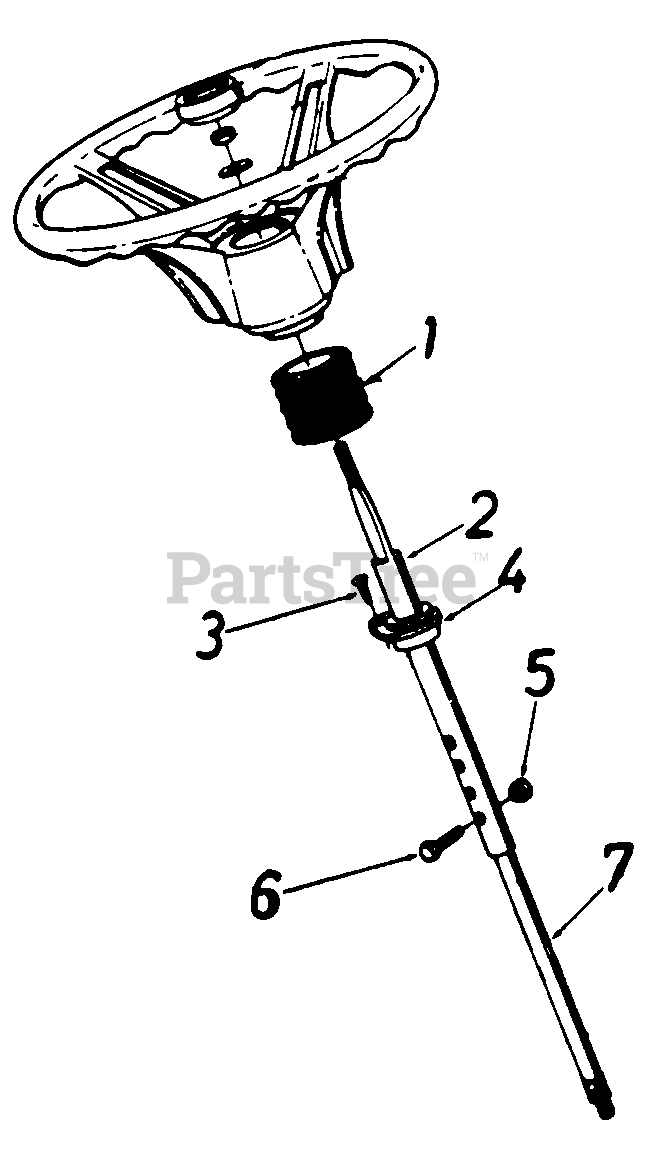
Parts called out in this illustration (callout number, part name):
1	Steering Bellow
2	Upper Steering Shaft
3	Oval Hd. C Sunk Scr. #10 x 5/8" Lg.
4	Fl Bearing .B9" I.D. x 1.36" O.D.
5	Hex L Nut 1/4 20 Thd.
6	Hex Bolt 1/4-20 x 1.31" Lg.
7	Lower Steering Shaft
